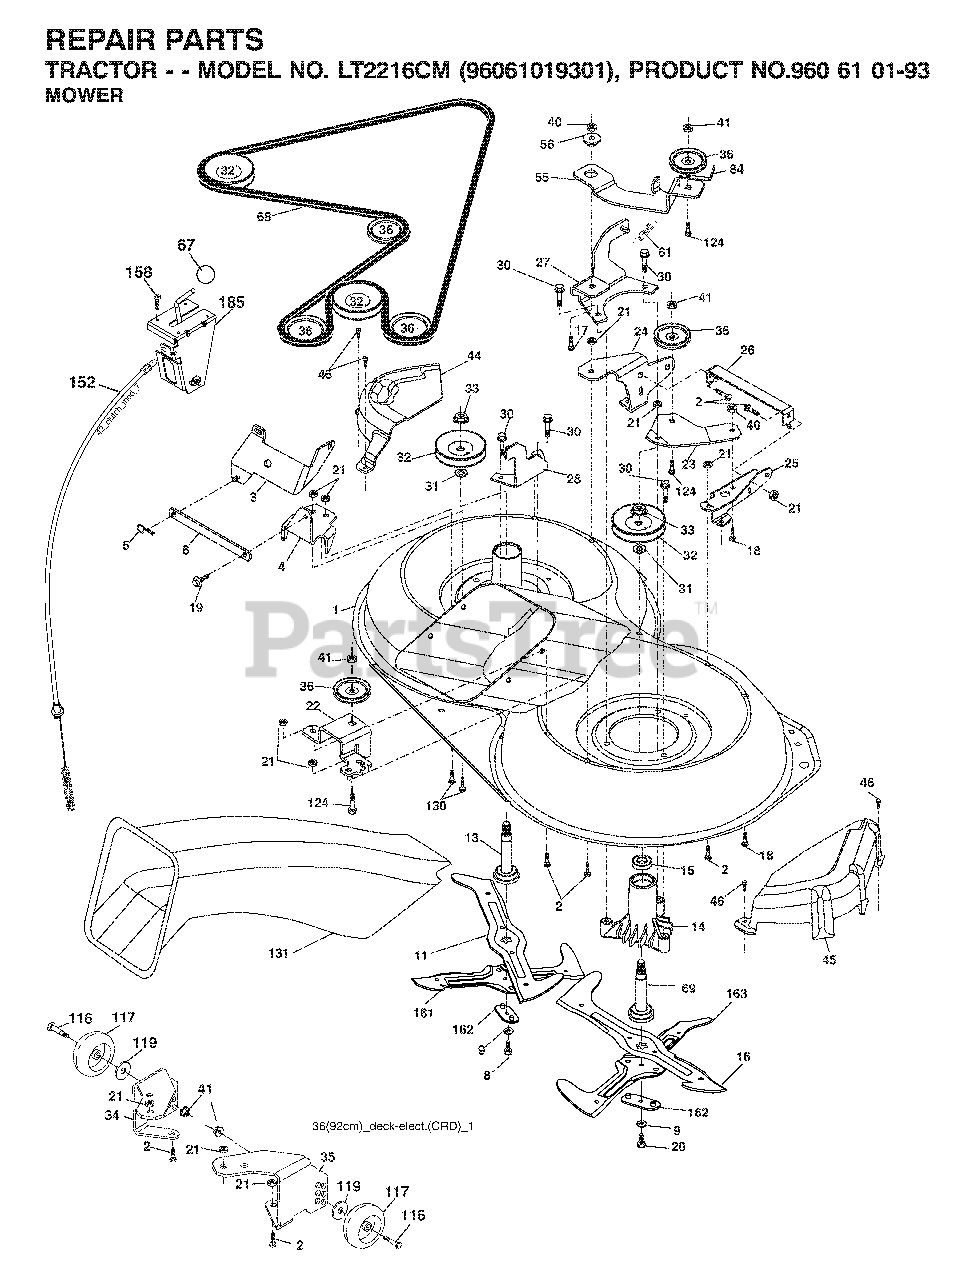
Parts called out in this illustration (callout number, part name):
2	BOLT
3	BRACKET
5	RETAINER-SPRNG RB
6	BAR SWAY
9	LOCKWASHER
10	WASHER.BLADE
13	SHAFT ASM VENT
14	HSG MANDREL
17	BOLT.3/8-14X1.25
19	BOLT SHD 5/16-18
21	LOCKNUT
24	BRACKET
25	BRACKET
28	BRACKET
30	SCREW, WASHER HEAD
31	WASHER.SPACER.MANDREL
32	PULLEY MANDREL
33	NUT.FLANGE.LOCK.TOP
36	PULLEY.IDLER.4.25
40	LOCKNUT
41	NUT LOCK FLG 3/8-16 UNC
45	MANDREL COVER
46	SCREW.1/4-20X5/8
56	SPACER.RETAINER.MOWER
67	KNOB T (3/8 HOLE)
69	SHAFT.ASM.W/LWR.BRG.RH.THREAD
84	KEEPER, BELT IDLER
116	BOLT.SHOULDER.3/8-16X3-5/8
117	WHEEL. GUAGE RALLY
118	NUT LOCK FLG 3/8-16 UNC
124	BOLT.3/8-16X1.50
131	CHUTE BAGGER
158	SCREW
185	HEAD ASM. CABLE CLUTCH
